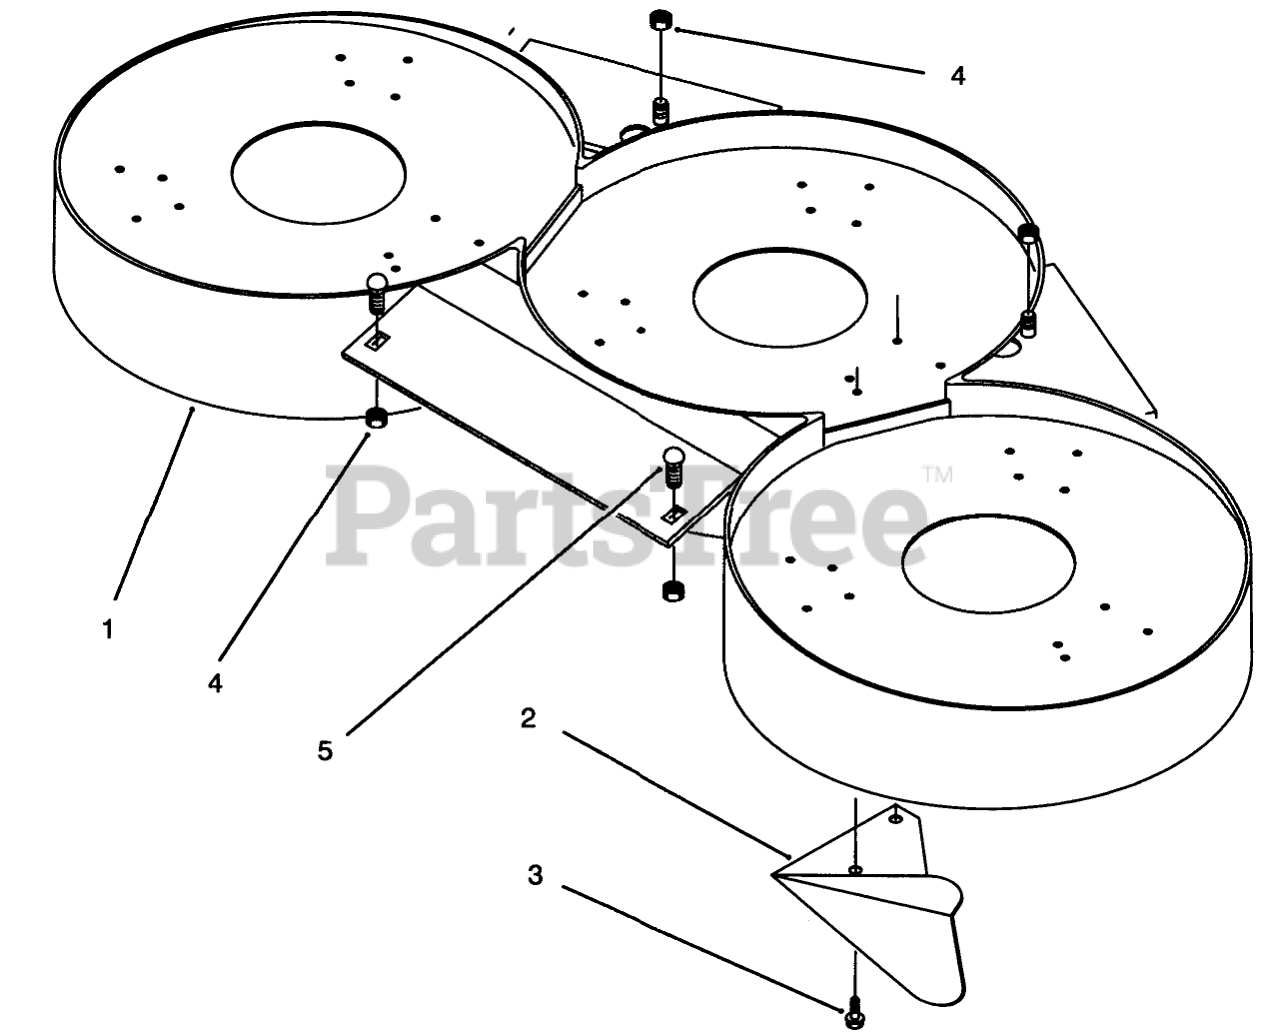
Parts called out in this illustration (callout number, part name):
1	Baffle
2	Kicker
3	Bolt
4	NUT-LOCK, NI
5	BOLT-CARR
